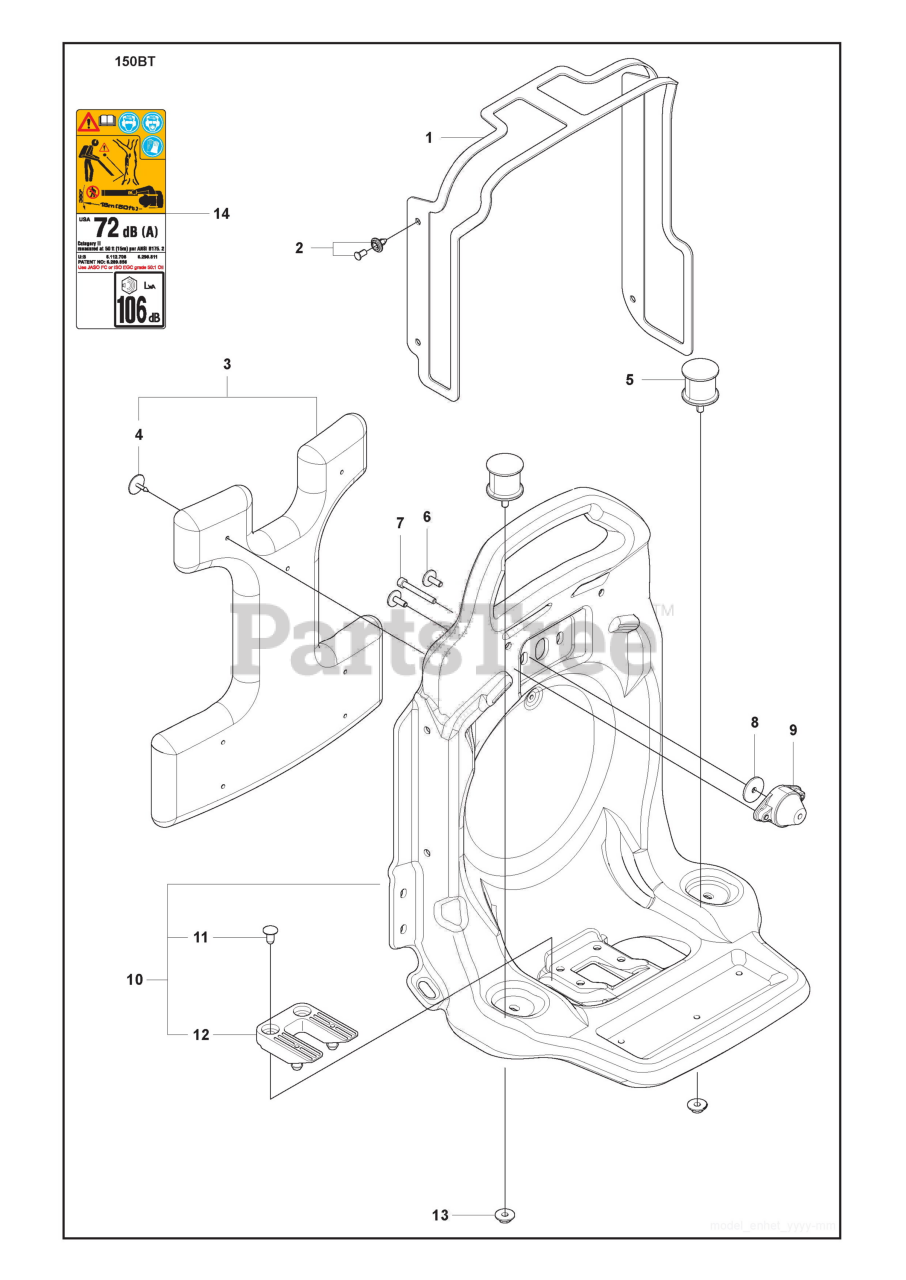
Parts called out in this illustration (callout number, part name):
2	CLIP
3	PAD COMP
4	CLIP
5	DAMPER
7	BOLT
8	WASHER
9	DAMPER
11	CLIP
13	NUT (M6)
14	LABEL CAUTION
